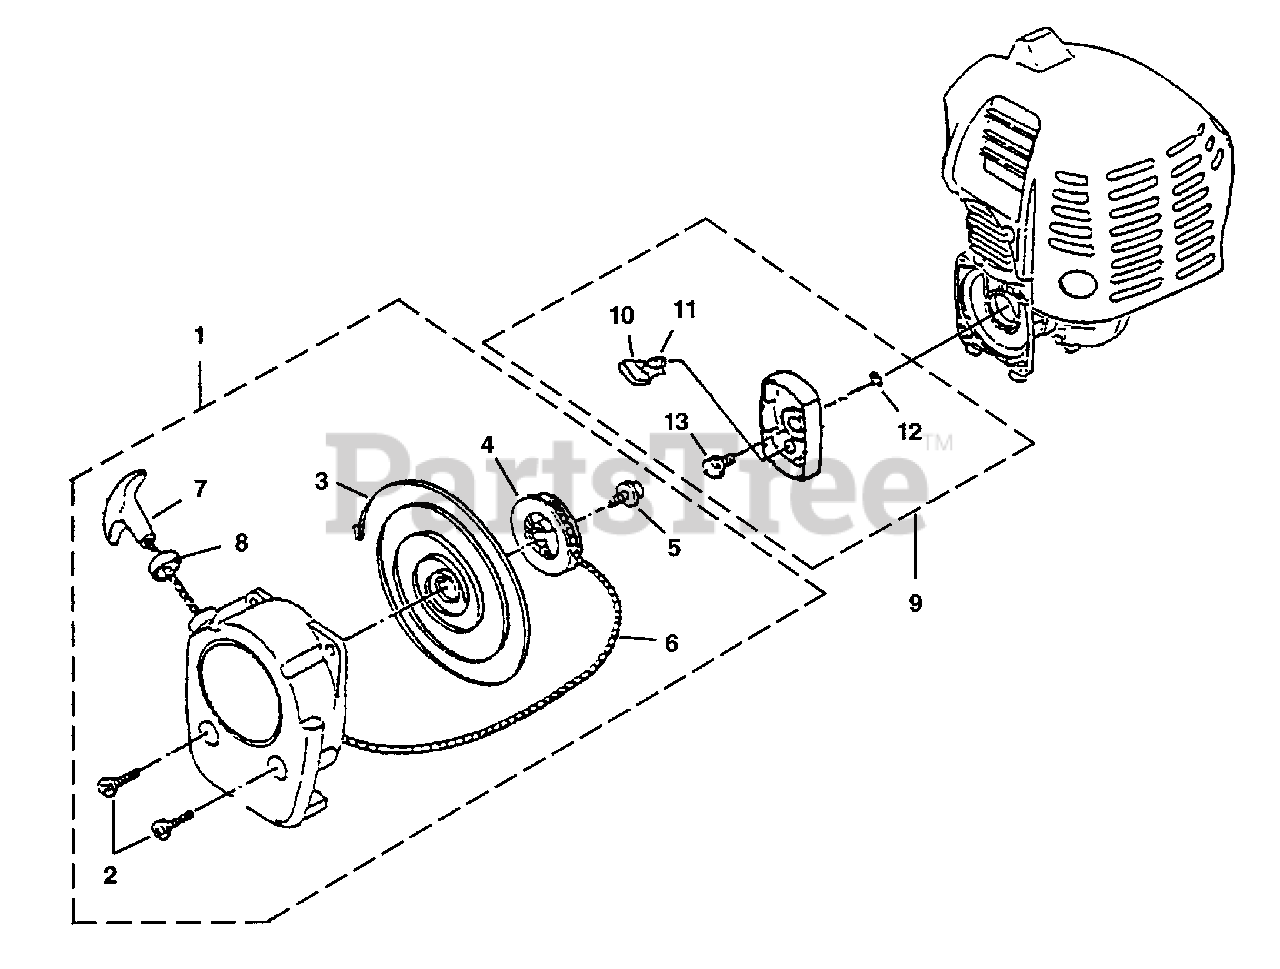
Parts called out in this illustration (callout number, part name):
1	STARTER COMPLETE
2	SCREW-Socket Hd (M5 x 30)
5	SCREW-Set
6	ROPE-Starter
8	DAMPER-Grip
9	STARTER CUP ASSEMBLY
11	SPRING-Return
13	BOLT ASSEMBLY (M6 x 14W)
